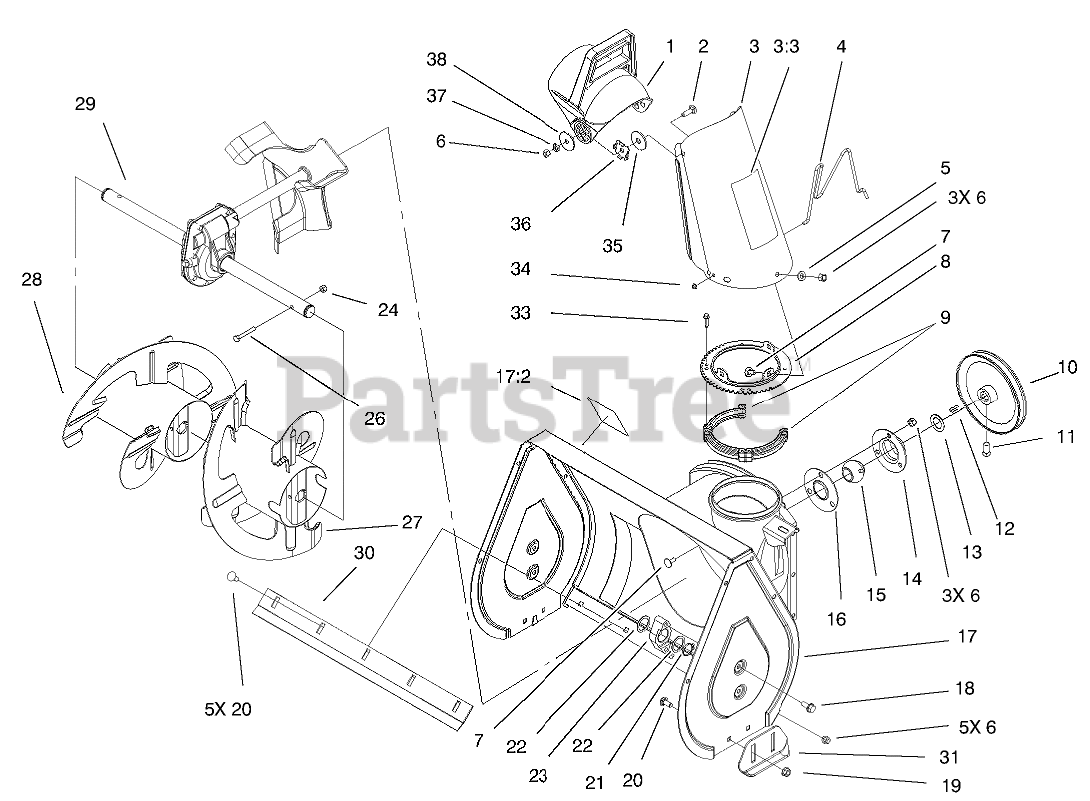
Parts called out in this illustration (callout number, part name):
1	CHUTE-DEFLECTOR
2	SCREW-CARR
3	Chute ASM (only on: 38073)
3	Chute ASM (only on: 38072)
3:3	Decal-Danger (only on: 38073)
3:3	Decal-Danger (only on: 38072)
4	WIRE-CHUTE
5	WASHER-PLAIN
6	NUT-LOCK, NI
7	SCREW-CARR
8	RING-CHUTE
9	RING-CHUTE, RETAINER
10	PULLEY
11	SCREW-SET, SQH
12	KEY-WOODRUFF
13	WASHER
14	FLANGE-CUP, BEARING
15	BEARING-BALL
16	FLANGE-CUP, BEARING
17	Auger Housing ASM (only on: 38072)
17	Auger Housing ASM (only on: 38073)
17:2	Decal-Warning, Auger (only on: 38073)
17:2	Decal-Warning, Auger (only on: 38072)
18	SCREW-HWHTF
19	NUT-HF
20	BOLT-CARR
21	RING-RETAINING
22	WASHER
23	BEARING-AUGER
24	NUT-LOCK, NI
26	SCREW-HH
27	24 INCH LH AUGER ASM
28	24 INCH RH AUGER ASM
29	24" GEAR CASE ASM
30	BLADE-SCRAPER, 24 INCH
33	SCREW-SPECIAL
34	NUT-PUSH
35	WASHER-RUBBER
36	PLATE-FRICTION
37	WASHER-BELLEVILLE
38	WASHER-FLAT
